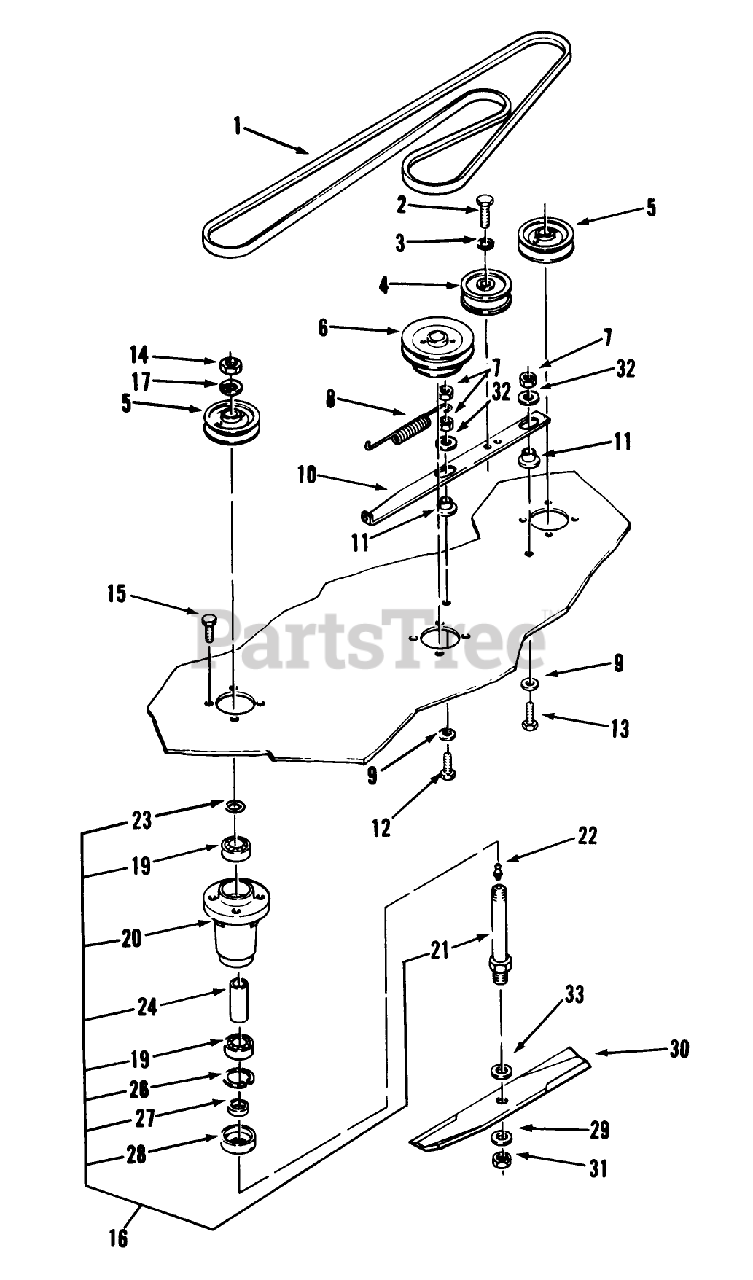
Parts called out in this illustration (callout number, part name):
1	V-BELT
2	SCREW-HH
3	WASHER-LOCK
5	PULLEY
6	PULLEY
7	NUT-LOCK, NI
8	SPRING-EXTENSION
9	WASHER
10	BAR-IDLER SUPPORT
11	SPACER-BUSHING
12	SCREW-HH
13	SCREW-HH
14	NUT-JAM
15	SCREW-HH
17	WASHER-LOCK
19	BEARING-BALL
20	HOUSING-SPINDLE
21	SHAFT-SPINDLE
22	FITTING-GREASE
23	O RING
26	RING-RETAINING
27	SPACER-BLADE
29	WASHER-FLAT
31	NUT-JAM
32	WASHER
